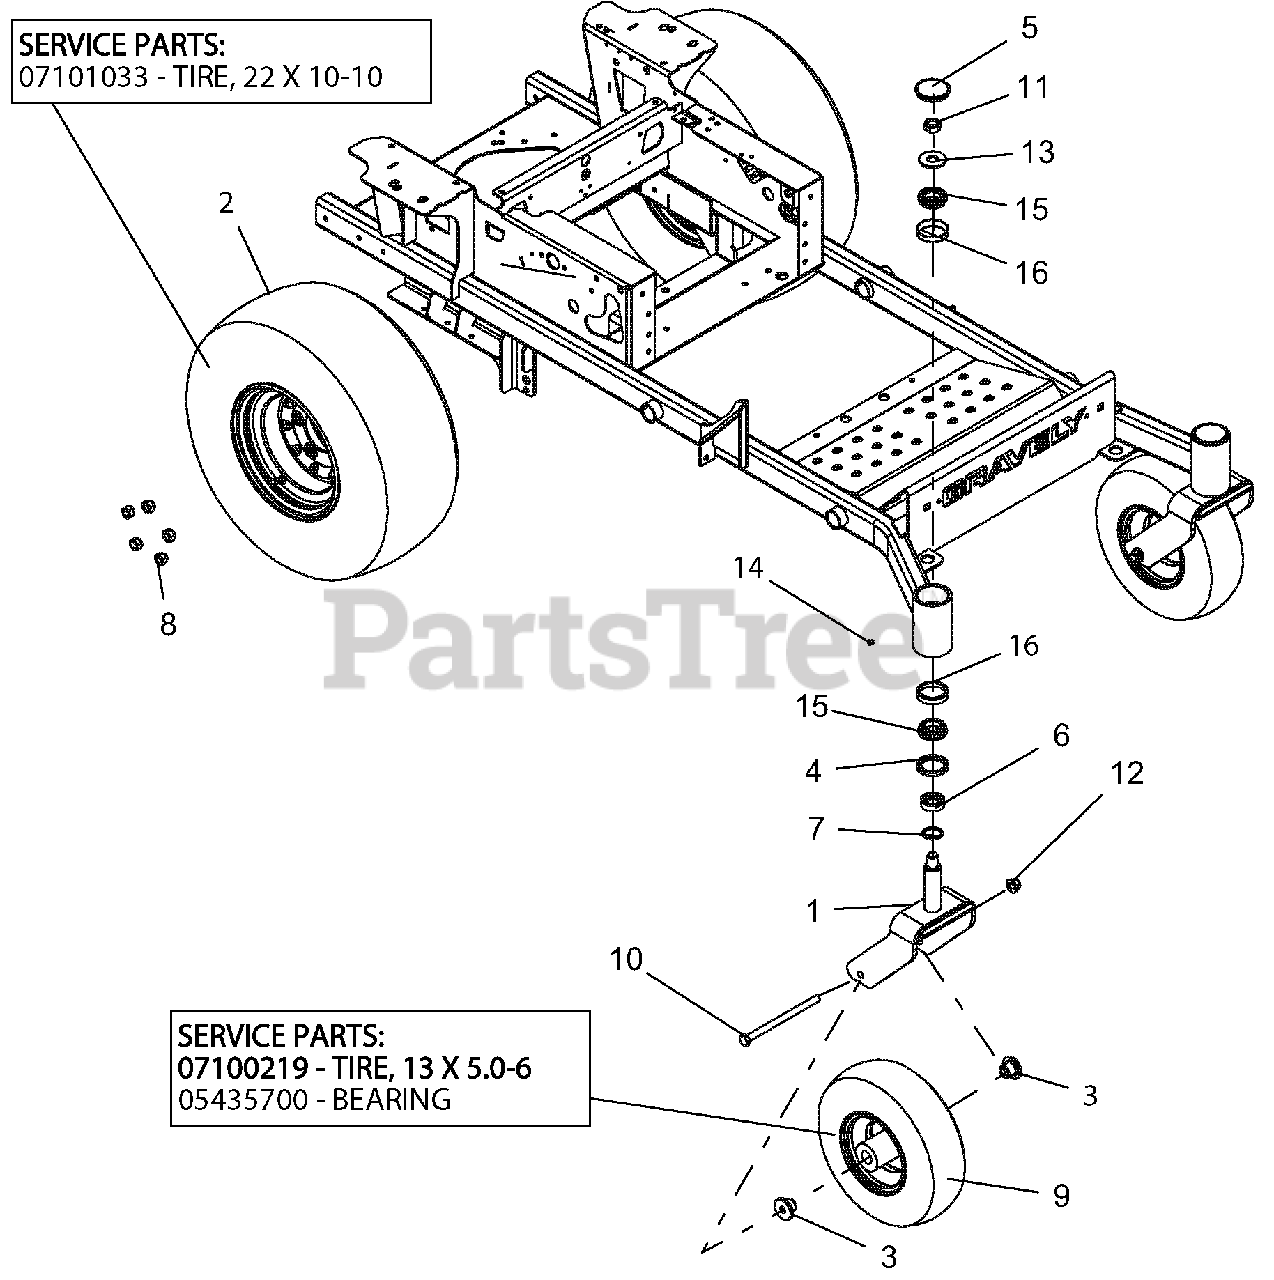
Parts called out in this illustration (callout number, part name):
1	WLDMT, CASTER FORK-RED
2	TIRE/WHEEL, ASM 22X10-10
2	TIRE, 22 X 10-10
3	SPACER, FRONT WHEEL
4	SEAL, OIL 1.75 X 2.332 X .312
5	CAP, DUST
6	SPCR, FRONT CASTER FORK
7	O-RING, .139 W X 1.234 ID
8	NUT, LUG .500-13
9	TIRE/WHEEL, ASM , 13X5-6
9	TIRE, 13 X 5.0-6
10	BLT-HEX .50-13X7.50 GR5 YWZC
11	@NUT-LK-CTR-JAM .75-16 YWZC
12	NUT-LK-NYL-FLG .50-13 YWZC
13	WSHR-FL-STL.812X2.00X.148YWZC
14	FITTING, .250-28 FLUSH MOUNT GREASE
15	BRG, CONE 1.250 X .660
16	BRG, CUP 2.328 X .465
